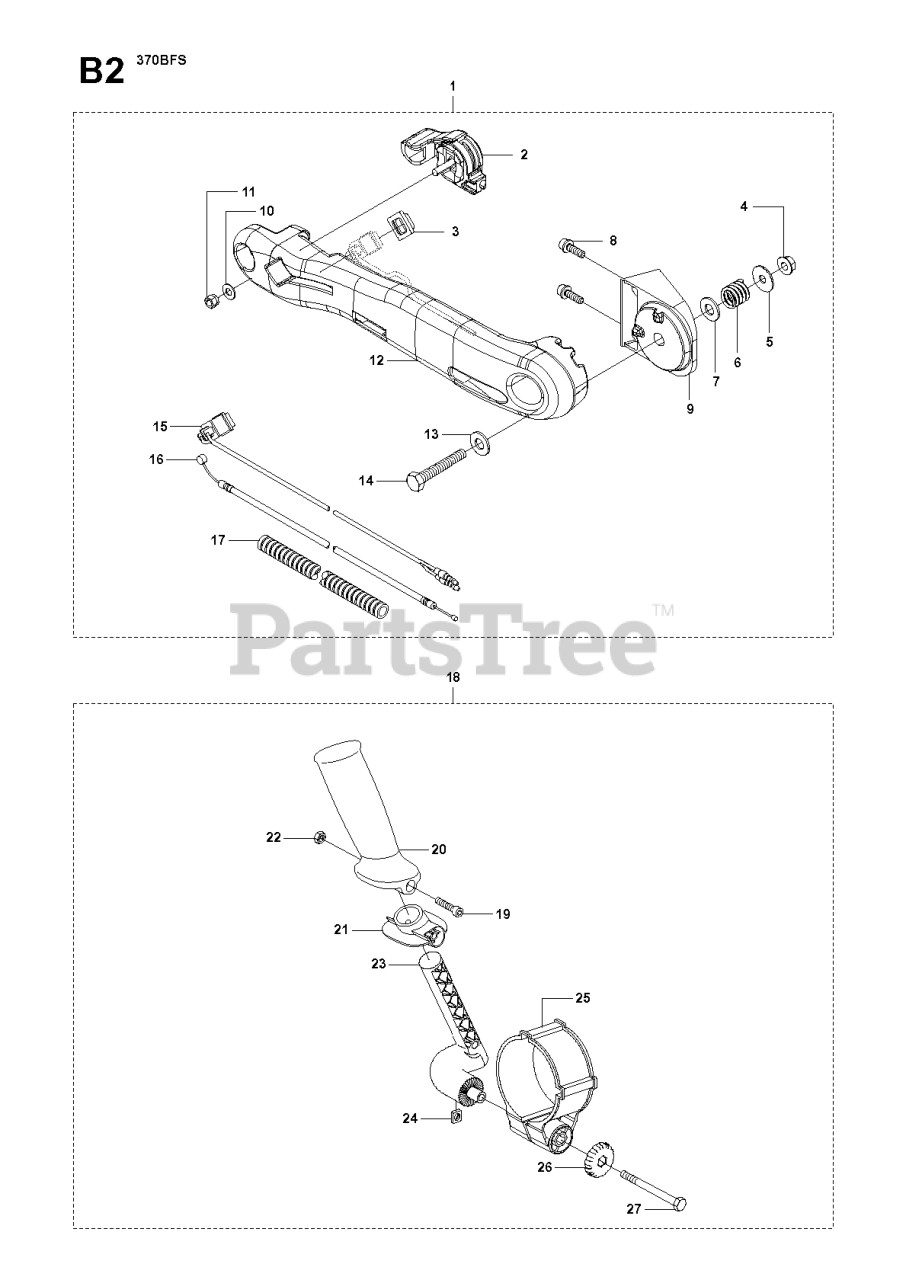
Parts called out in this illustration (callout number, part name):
1	HANDLE ASSY
3	CAP SWITCH
4	NUT 8488646000
5	WASHER Z349525440
10	WASHER
15	KILL SWITCH
16	RP_CABLE COMP
22	NUT
23	BRACKET
24	SQUARE NUT M5
26	KNOB
